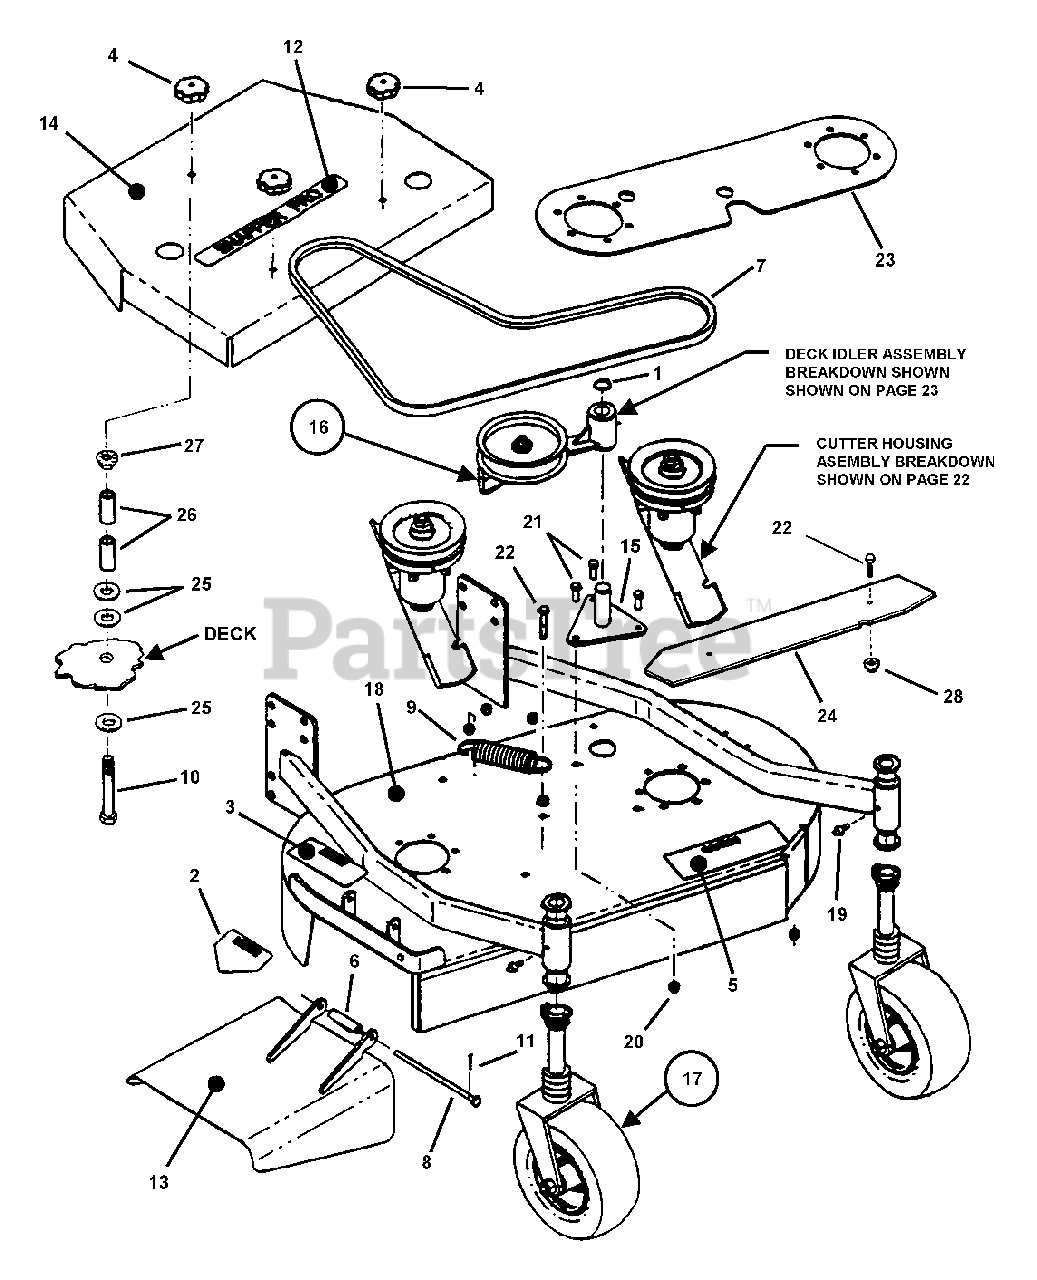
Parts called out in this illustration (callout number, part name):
1	SNAP-Ring, 1" External
2	DECAL, Warning (CPSC Cut Finger)
3	DECAL, Warning
4	KNOB, Hood
5	DECAL, Caution- Operator Instruction
6	SPRING, Chute
7	V-BELT, Deck Drive 36"
8	HINGE PIN, Chute
9	SPRING, Idler
10	SCREW, 5/16-18 x 4-1/2" Hex Head Cap, Grade 5
11	PIN, 3/32 x 1" Cotter
12	DECAL, Snapper Pro
13	DEFLECTOR, 36" (Weldment)
14	COVER, 36"
15	PIVOT, Idler (Weldment)
16	ASSEMBLY, Idler Arm 36"
17	ASSEMBLY, Caster (Red)
18	ASSEMBLY, Deck 36" Fixed Height
19	FITTING, Lube 1/4-28 Straight
20	NUT, 3/8-16 HEX NYLON LOCK
21	BOLT, 3/8-16 X 1" GD5 CZ
22	BOLT, 3/8-16 X 2, GD5, CZ
23	PLATE, Stiffener (7 Gage)
24	PLATE, Ballast
25	WASHER, 3/8" I.D. Flat
26	SPACER
27	NUT, 5/16-18 Hex Flange Lock, Grade 5
28	NUT, 3/8-16 HEX SERRATED FLANGE
